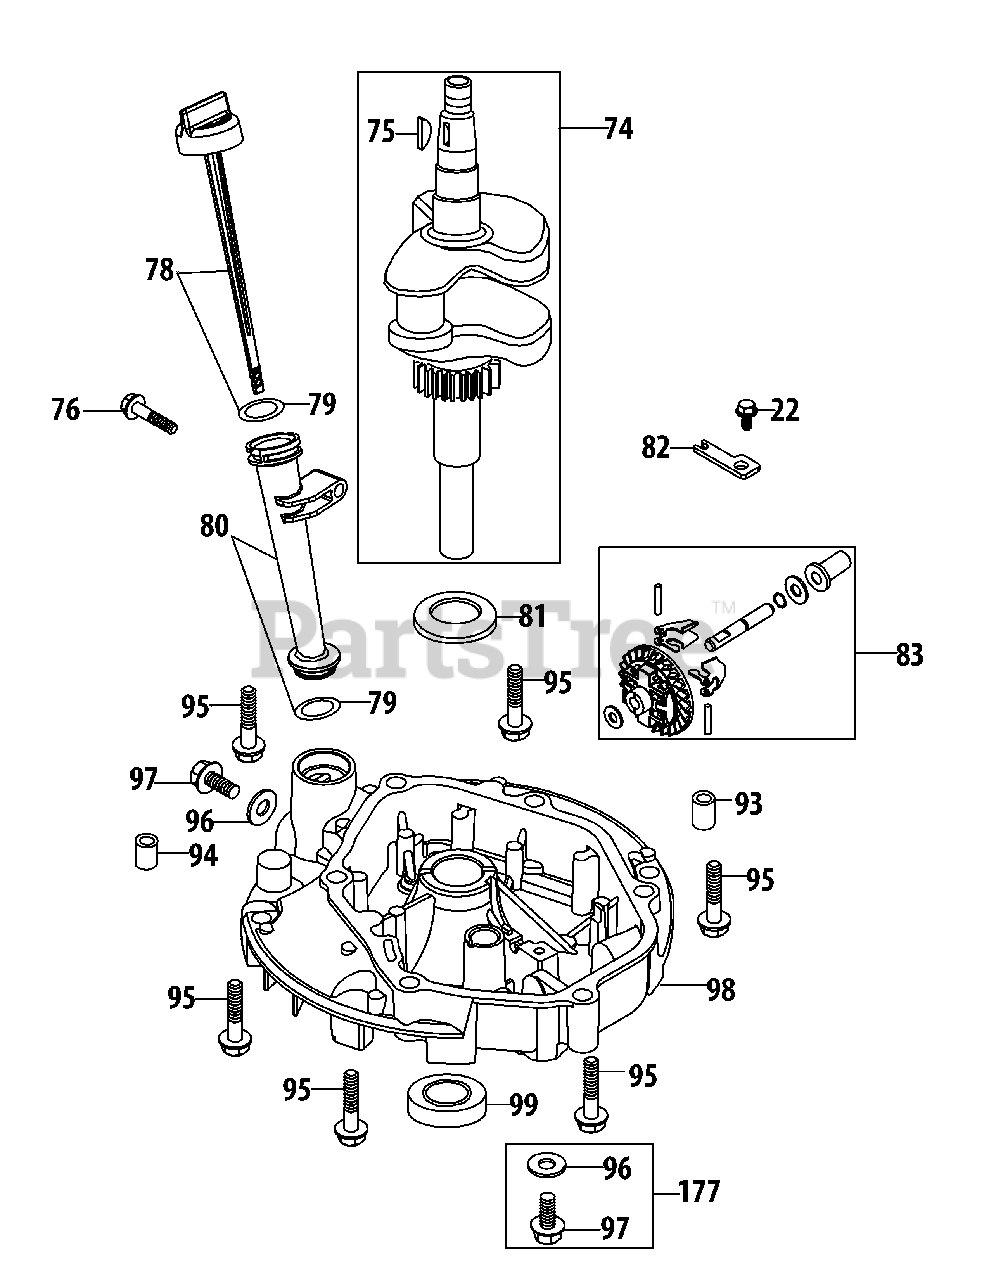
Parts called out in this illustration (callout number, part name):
22	Bolt M6X14 Multi-Purpose
74	Crankshaft Assembly
75	Woodruff Key
76	Bolt M6X35 Af Base/Brake/Dipstick
78	Dipstick Assembly
79	Dipstick / Oil Fill Tube O-Ring
80	Oil Filler Tube Assemlby
81	Crankshaft Thrust Washer
82	Governor Gear Mounting Plate
83	Governor Gear/Shaft Assembly
93	Crankcase Cover Dowel Pin 7×14
94	Crankcase Cover Dowel Pin 9×14
95	Bolt M8X50 Fuel Tank/P70 Crankcase
96	Oil Drain Plug Washer
97	Oil Drain Plug
98	Crankcase Cover
99	Lower Crankshaft Seal
177	Oil Drain Plug and Washer Ass'y
